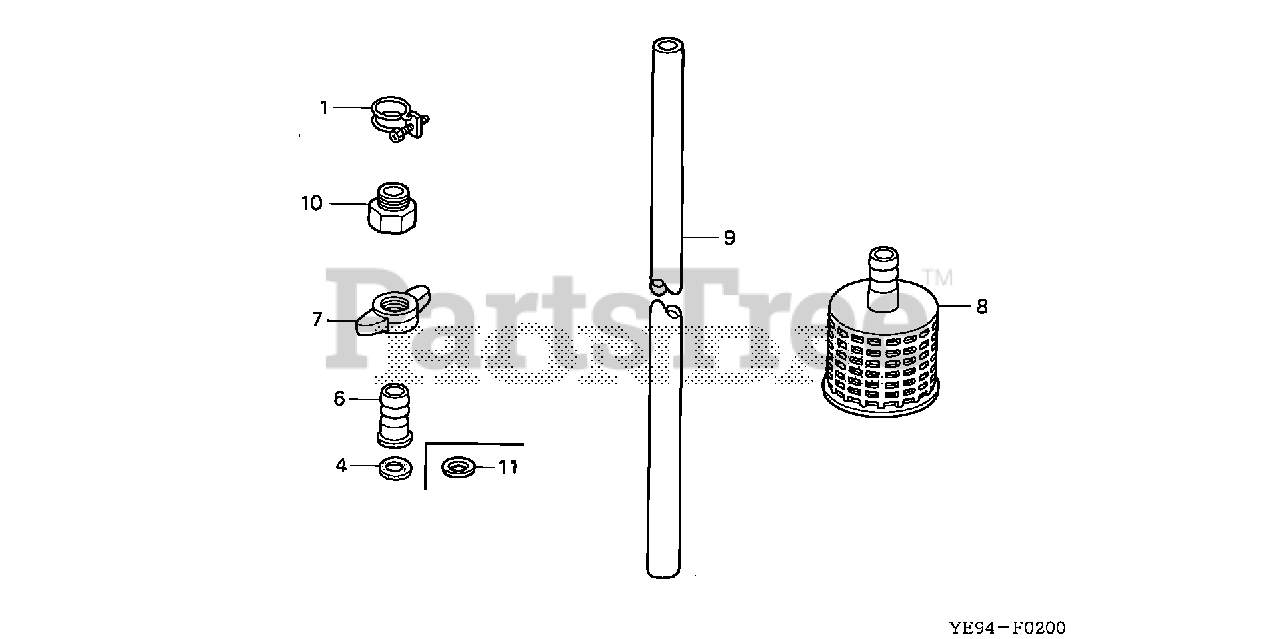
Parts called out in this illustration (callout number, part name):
1	BAND, HOSE
4	GASKET, CONNECTOR (MALE)
6	COUPLING, HOSE
7	RING, HOSE CLAMP
8	STRAINER
9	HOSE, SUCTION (5M)
10	ADAPTER
11	GASKET, COUPLING
